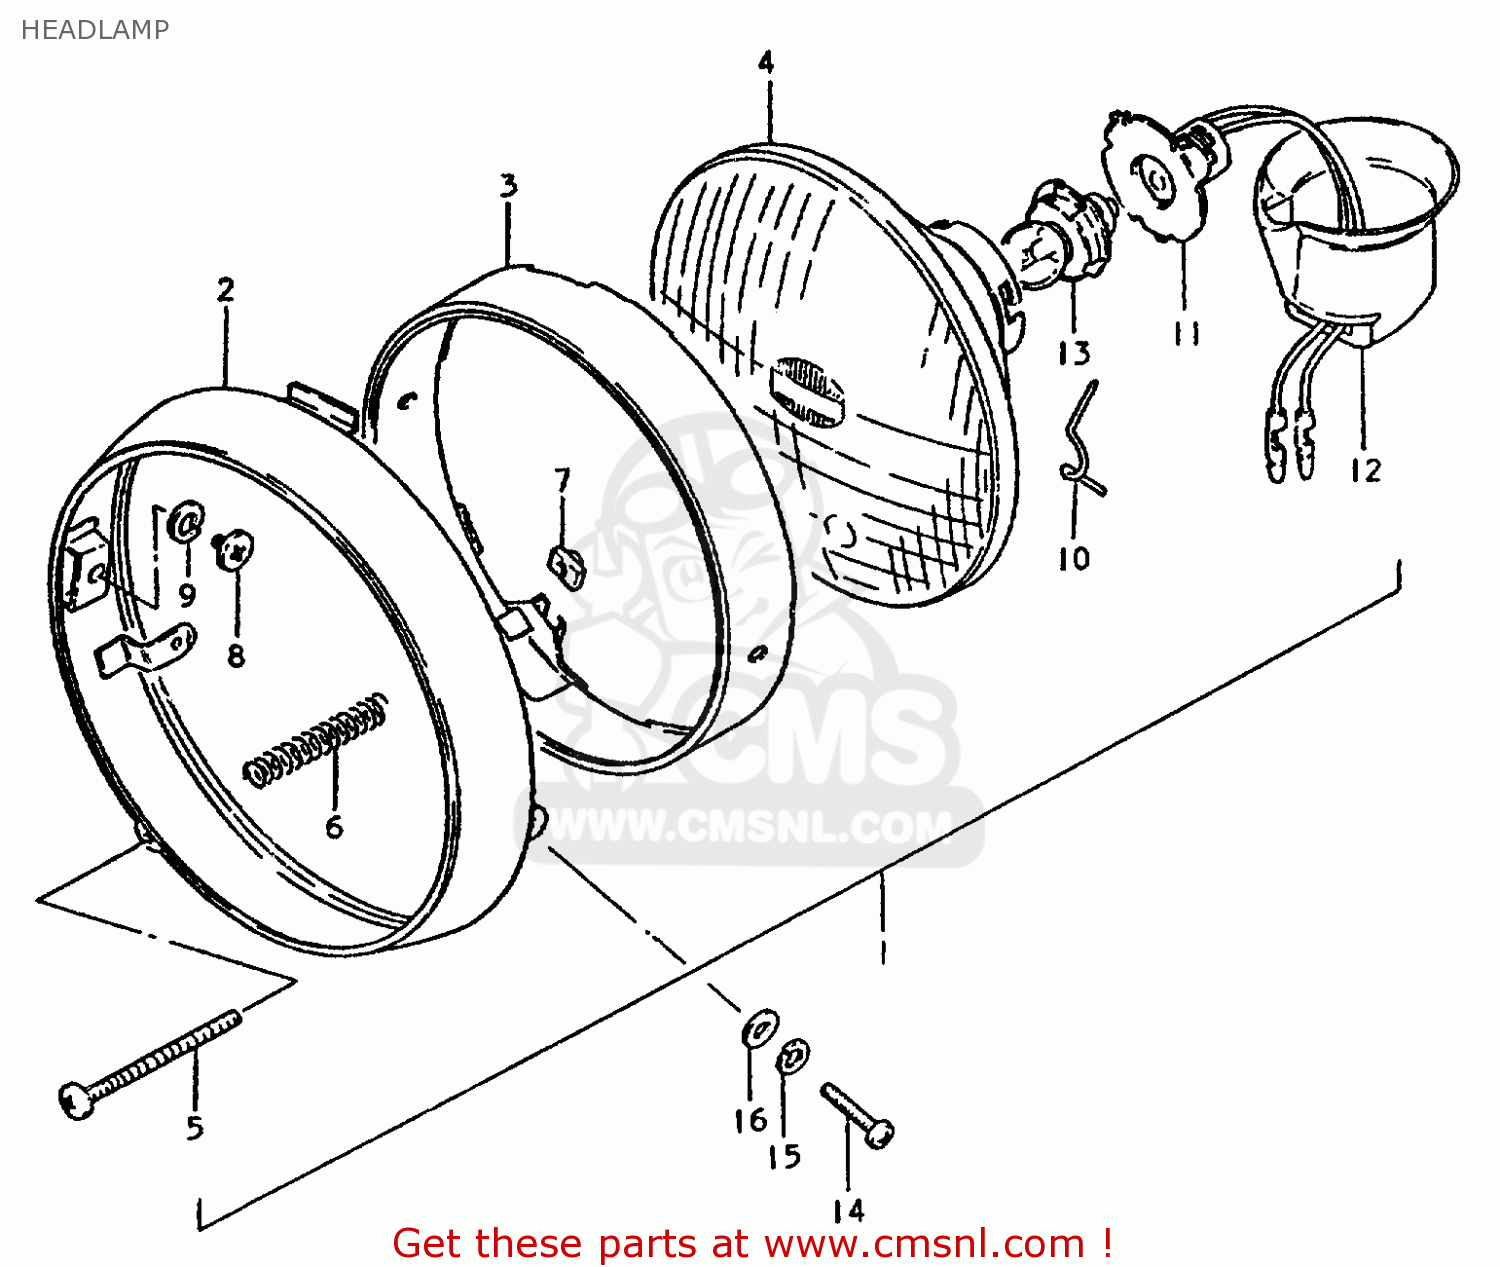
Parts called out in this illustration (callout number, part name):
1	HEADLIGHT ASSY
2	RIM
3	RETAINER
4	UNIT
5	SCREW,HEADLAMP ADJUST
6	SPRING,ADJUSTING
7	NUT
8	SCREW
9	LOCK WASHER
10	SPRING
11	SOCKET
12	COVER
13	BULB (6V,15W)
14	SCREW
15	LOCK WASHER
16	WASHER
